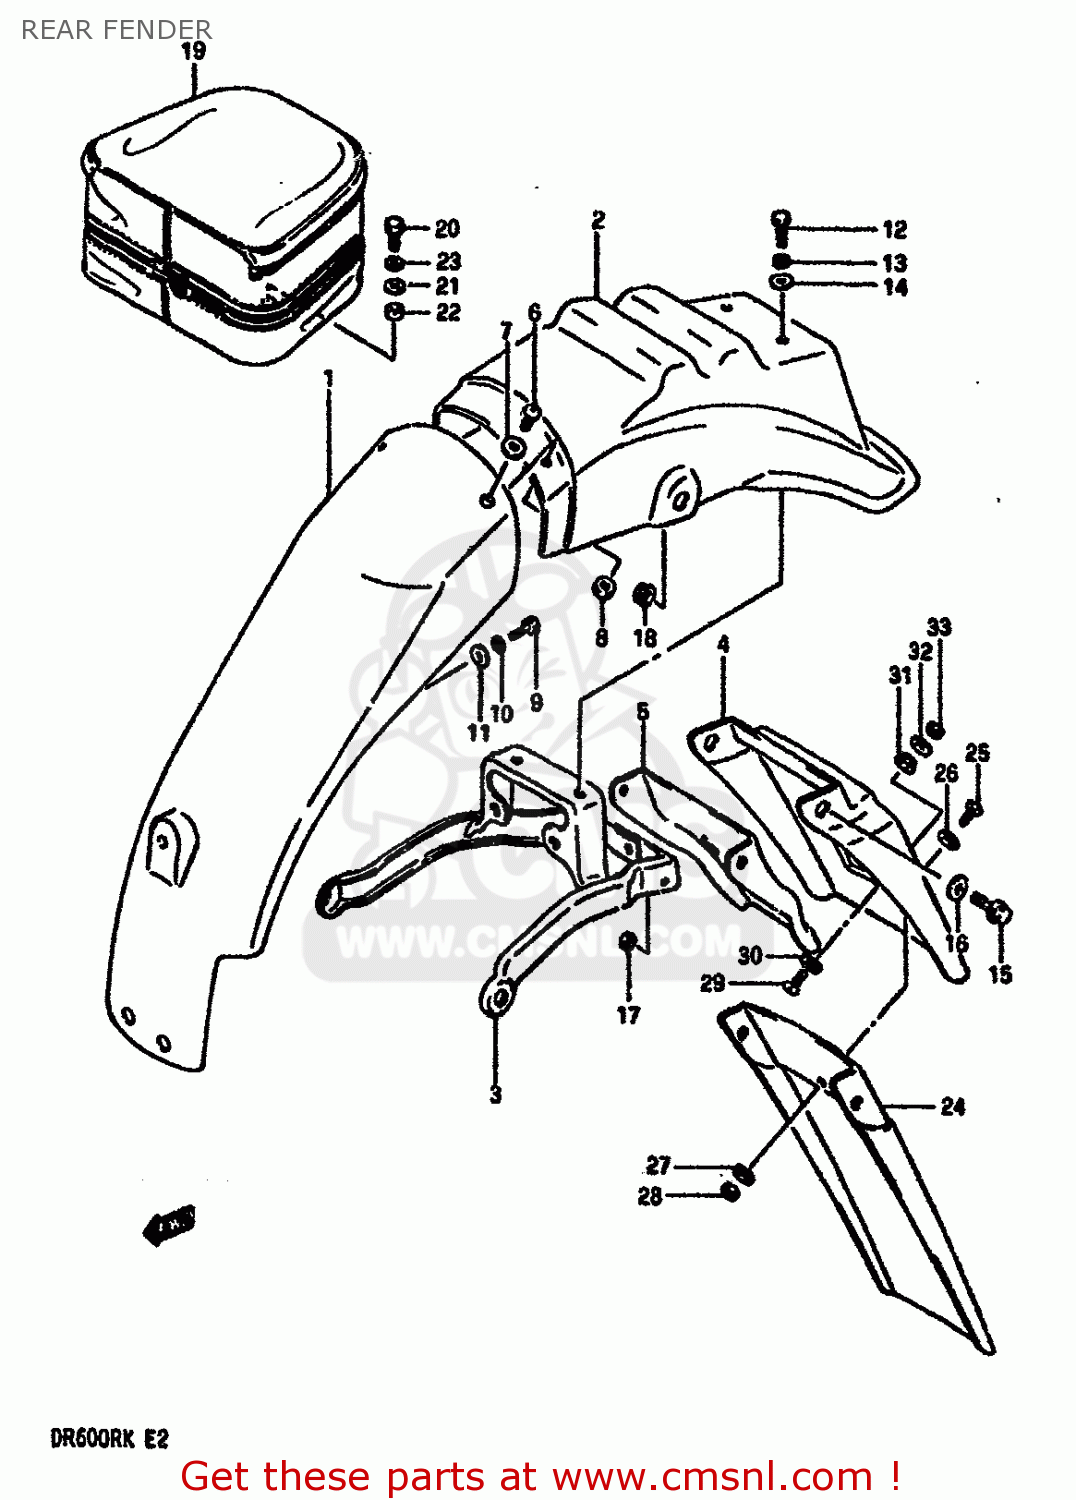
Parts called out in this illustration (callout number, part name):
1	BODY,REAR FENDER,FRONT
2	BODY, REAR (WHITE)
3	REINFORCEMENT,REAR FENDER
4	EXTENSION
5	REINFORCEMENT,REAR FENDER EXTENSION
6	SCREW, FRONT & REAR
7	WASHER
8	NUT 8MM
9	BOLT 6X16
10	WASHER,LOCK
11	WASHER
12	BOLT
13	WASHER,LOCK
14	WASHER
15	BOLT
16	WASHER
17	NUT
18	NUT
19	BAG ASSY, SEAT TAIL (GRAY/BLUE)
20	BOLT
21	WASHER
22	SPACER
23	WASHER,LOCK
24	MUD GUARD
25	SCREW 6X12
26	WASHER(6.5X16X1.2)
27	WASHER,LOCK
28	NUT
29	SCREW
30	WASHER
31	WASHER
32	WASHER
33	NUT
